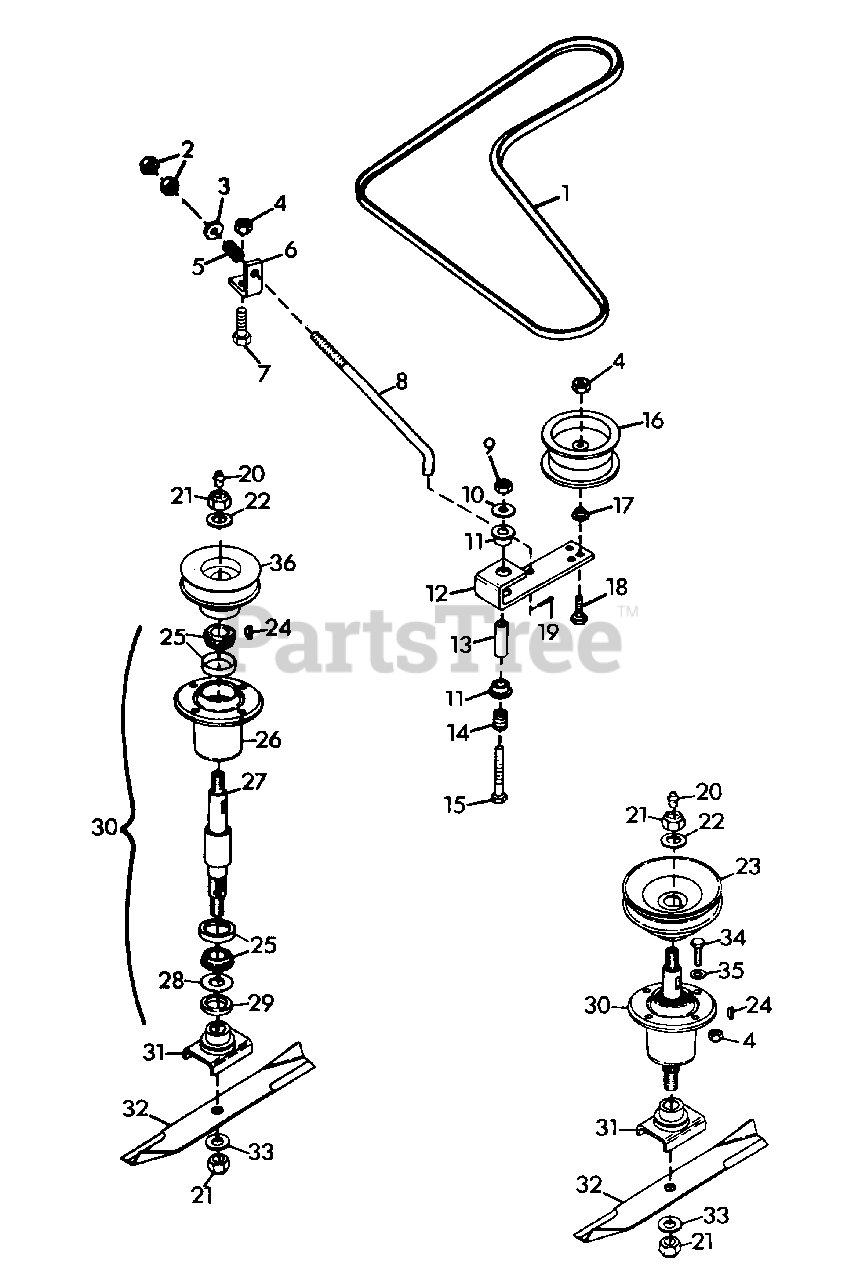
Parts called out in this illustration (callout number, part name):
1	BELT, PRO-32 MOWER
2	NUT, HEX 3/8-24
3	WASHER, FLAT .406X.812X.065
4	NUT, LOCK 3/8-16
5	SPRING, COMPRESSION 1X.78X338 LB/N
6	BRACKET, BELT TENSIONER
7	BOLT, HEX 3/8-16X.875
8	ROD, IDLER
9	NUT, LOCK 1/2-13
10	WASHER, FLAT .531X1.250X.100
11	BUSHING, NYLON .760X1.00X.600 FLG.
12	ARM, IDLER PIVOT
13	SPACER
14	SPRING, COMPRESSION 1X.80X36 LB/N
15	BOLT, HEX 1/2-13X3.25
16	PULLEY, IDLER
17	BUSHING
18	BOLT, HEX 3/8-16X2.25
19	PIN, COTTER .09X.75
20	FITTING, LUBE 1/8
21	NUT, LOCK 5/8-11
22	WASHER, FLAT .687X1.312X.122
23	SHEAVE, SPINDLE
24	KEY, WOODRUFF 1/4X1 HARD #15
25	ASSEMBLY, BEARING
26	HOUSING, BEARING
27	SHAFT, SPINDLE
28	WASHER, FLAT .975X1.970X.030
29	SEAL, STEEL
30	ASSEMBLY, SPINDLE
31	WELDMENT, BLADE CRADLE
32	BLADE
33	WASHER, FLAT .656X1.312X.095
34	BOLT, HEX 3/8-16X1.25
35	WASHER, FLAT .438X1.00X.083
36	SHEAVE, SPINDLE
